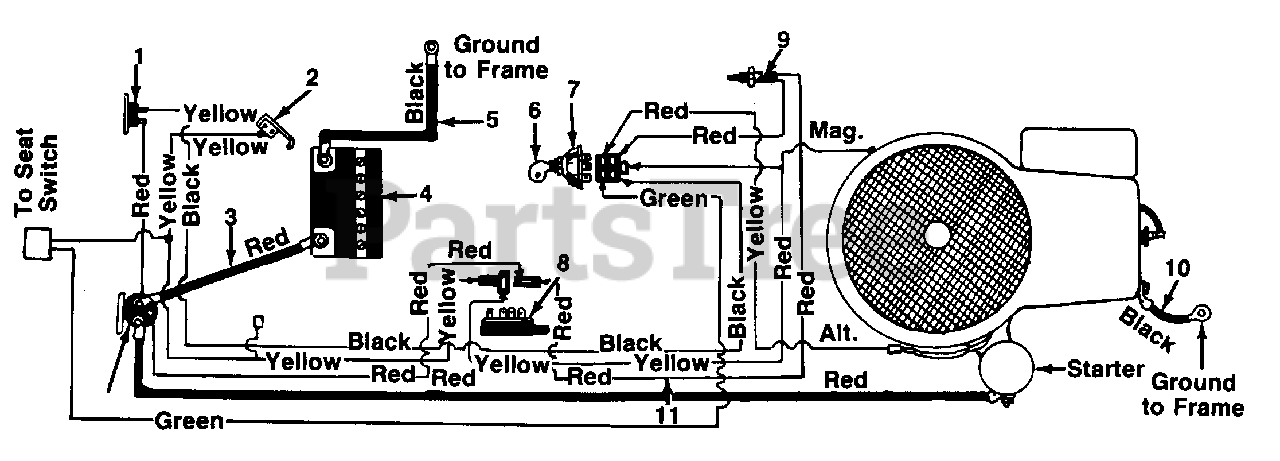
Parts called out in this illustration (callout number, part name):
1	Circuit Breaker
2	Reverse Safety Switch
3	Electric Wire w/Boot
4	12V-Battery
5	Ground Wire 9.0" Lg.
6	Ignition Key
7	Ignition Switch
8	Safety Switch
9	Safety Switch
10	Ground Wire 7.25" Lg.
11	Wire Harness
